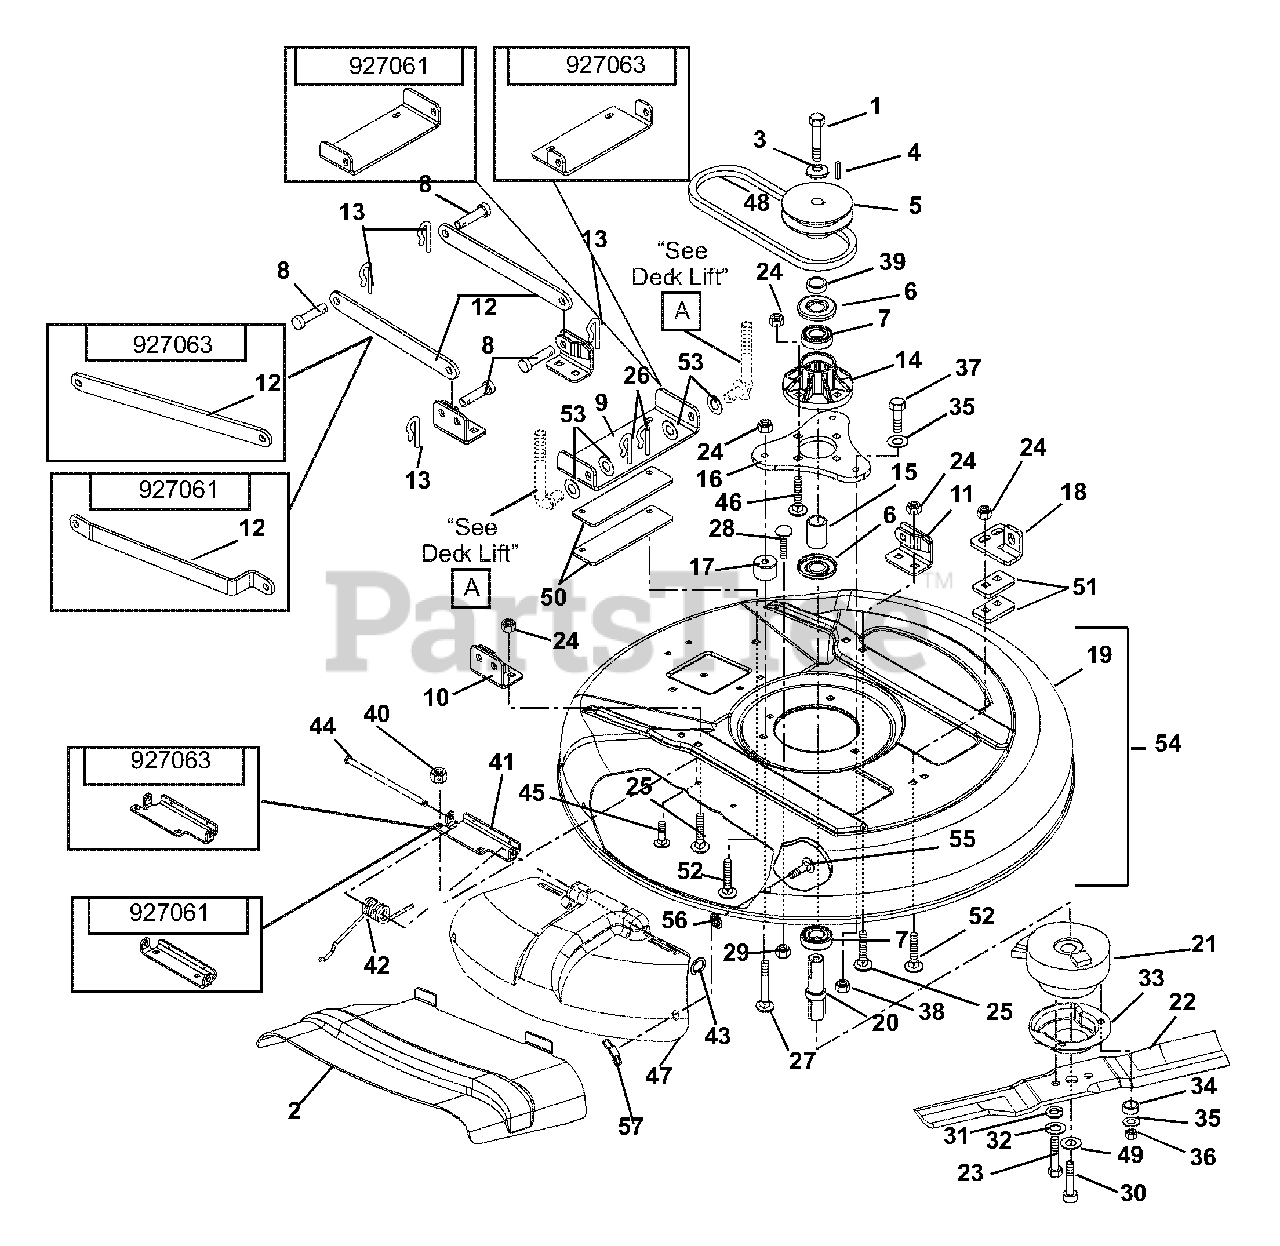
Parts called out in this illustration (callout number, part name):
1	BLT-HEX .38-16X1.00 YZ GR8
2	DISCHARGE CHUTE
3	WASHER, CUPPED SERRATED, .375
4	KEY, SQ .25 X .38 X .25
5	SHEAVE, 4.25 DIA A-SECTION
6	SHEAVE, 4.75 DIA A-SECTION
6	BEARING SLINGER
7	BRG-BALL 1.0X2.0X.56 (1641)
8	PIN-CLEV .494X1.00 BLKZC
9	BRKT, REAR HANGER (28" DECK)
9	BRKT, FRONT LIFT (32" DECK)
10	BRKT, 28" DECK STABILIZER
10	WLDMT-DECK LINK (RH)
11	WLDMT-DECK LINK (RH)
11	WLDMT-DECK LINK (LH)
12	STABILIZER, 28" DECK (RH)
12	LINK STABILIZER 32"
13	CLIP, SPRING
14	ASSY-SPINDLE HSG
15	SPACER, 1.001 X 1.25 X 1.76
16	SPINDLE MOUNT PLATE
17	SPACER-MOUNTING PLATE
18	BRKT, FRONT HANGER (28" DECK)
18	BRKT, FRONT LIFT (32" DECK)
19	DECK, 28" RER
19	DECK, RER/SZ 32"
20	SHAFT, 28" AND 32" INPUT
21	KIT, CLUTCH (1232 RER)
21	KIT, CLUTCH (1028 RER)
22	BLADE-CUTTING 28"
22	BLADE, 32" RER/ZS
23	BLT-HEX M10X1.25X30 CLS 10.9
24	NUT-LK-TOP-FLG .38-16 BLKZC
25	BLT-RDHDSQNK .38-16X.75 G5BZ
26	PIN, HAIR, EXT - #16 YWZC
27	BLT-RDHDSQNK .38-16X2.25 G5BZ
28	@BLT-RDHDSQNK .31-18X1.50 G5YZ
29	@NUT-SPNLK-FLG .312-18 YWZC
30	SCR-SKN .5-20X1.25 BTNHD
31	WSHR-LK M 10MM YZ
32	WSHR-FL-STL .406X1.00X.188 YWZ
33	SHIELD, DEBRIS
34	BSHG, SPCR .752X.877X.50 BRZ
35	@WSHR-FL-STL.38X.875X.083 YWZC
36	@NUT-LK-NYL .38-16 YWZC
37	BLT-HEX .38-16X3.00 GR5 FTH YZ
38	@NUT-SPNLK-FLG .375-16 YWZC
39	SPACER 1.008X1.377X.509 ST
40	NUT-LK-FLG .250-20 PL BLK
41	BRKT, 28" MULCH COVER HINGE
41	BKT, HINGE
42	SPRING, TORSION
43	RG-RTNG-EXT .312X.025
44	PIN, HINGE
45	@BLT-RDHDSQNK .25-20X.75 G5YZ
46	@BLT-RDHDSQNK .38-16X1.25 G5YZ
47	COVER, 28" DECK MULCH
47	MULCH COVER, 32" DECK
48	V-BELT, HA-WRAPPED
49	WASHER, FLT STL .5X1.75X.187
50	PLATE, 32" REAR HANGER SPACER
51	PLATE, 32" FRONT HANGER SPCR
52	@BLT-RDHDSQNK .38-16X1.25 BKZC
53	WSHR-FL-STL .518X2.0X.105 YWZC
54	KIT, 28" DECK SERVICE ASSY
54	KIT, 32" DECK SERVICE ASSY
55	BLT-RDHDSQSHK.31-18X.75 GR2 YW
56	NUT-PUSH .312
57	NUT-NYLK WING .312-18 YWZC
